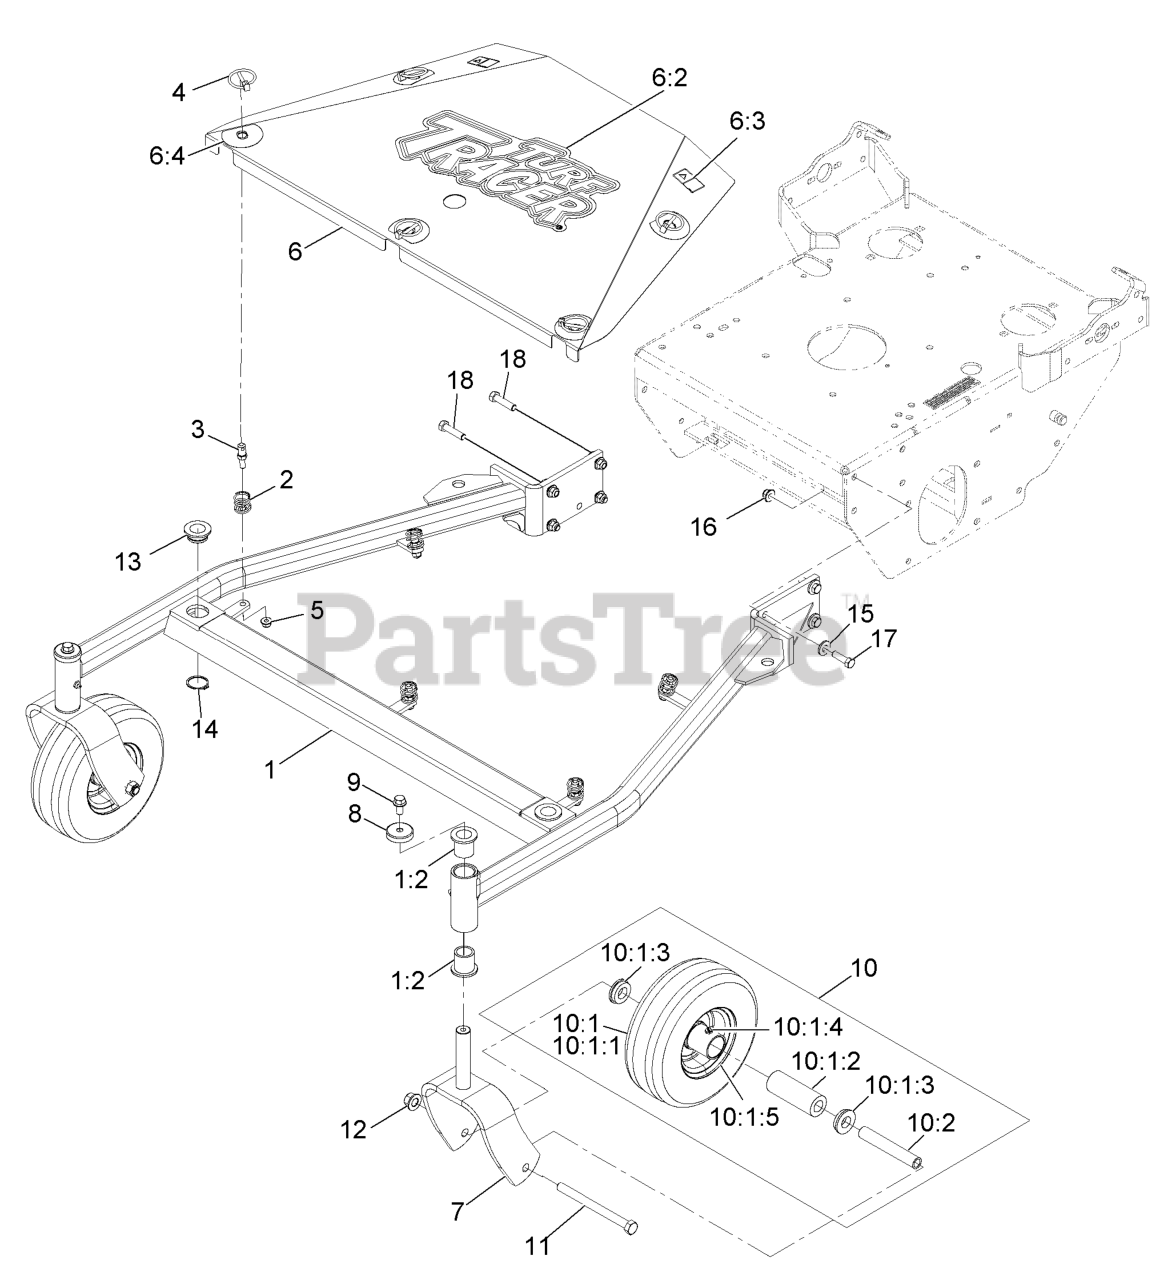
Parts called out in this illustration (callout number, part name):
1	ASM, FRAME W/ BUSHINGS, 5
1:2	BEARING-FLANGED
3	PIN-SPRING
4	PIN-LYNCH
5	NUT-HF, NI
6	ASM, SHIELD W/ DECALS, 52
6:2	DECAL,TTH MODEL
6:3	DECAL-WARNING
6:4	DECAL-SCRATCH COVER
7	FORK, CASTER
8	CAP, DUST
9	SCREW-HHF
10	KIT, SP CASTER WHEEL REPL
10:1	Wheel And Tire ASM
10:1:1	Tire
10:1:2	BEARING
10:1:3	BUSHING
10:1:4	FITTING-GREASE
10:1:5	Wheel
11	SCREW-HH
12	Nut-Lock 1/2-13
13	BUSHING-DECK
14	RING-RETAINING
15	WASHER-BELLEVILLE
16	NUT-HF, NI
17	SCREW-HH
18	SCREW-HH
